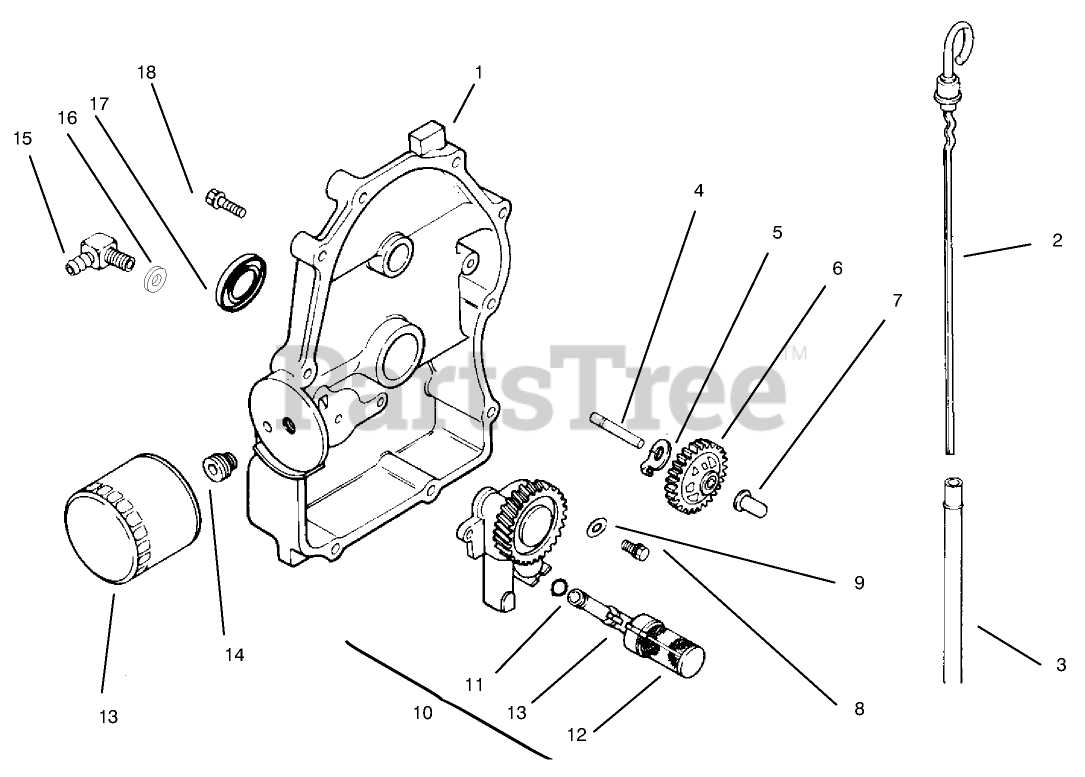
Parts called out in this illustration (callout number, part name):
1	Plate-Closure (Incl. Ref. # 2-7, 10-12, 16 & 17)
2	Dipstick
3	Tube-Dipstick
4	Shaft-Gear, Governor
5	Tab-Locking
6	Kit-Governor Gear Asm (Incl. Ref. # 7)
7	Pin-Governor
8	Screw
9	Washer
10	Oil Pump Assembly (Incl. Ref. # 11-12)
11	O-Ring
12	Pick-Up-Oil
13	Filter-Oil
14	Nipple-Filter, Oil
15	Connector
16	O Ring
17	Seal-Oil
18	Screw
